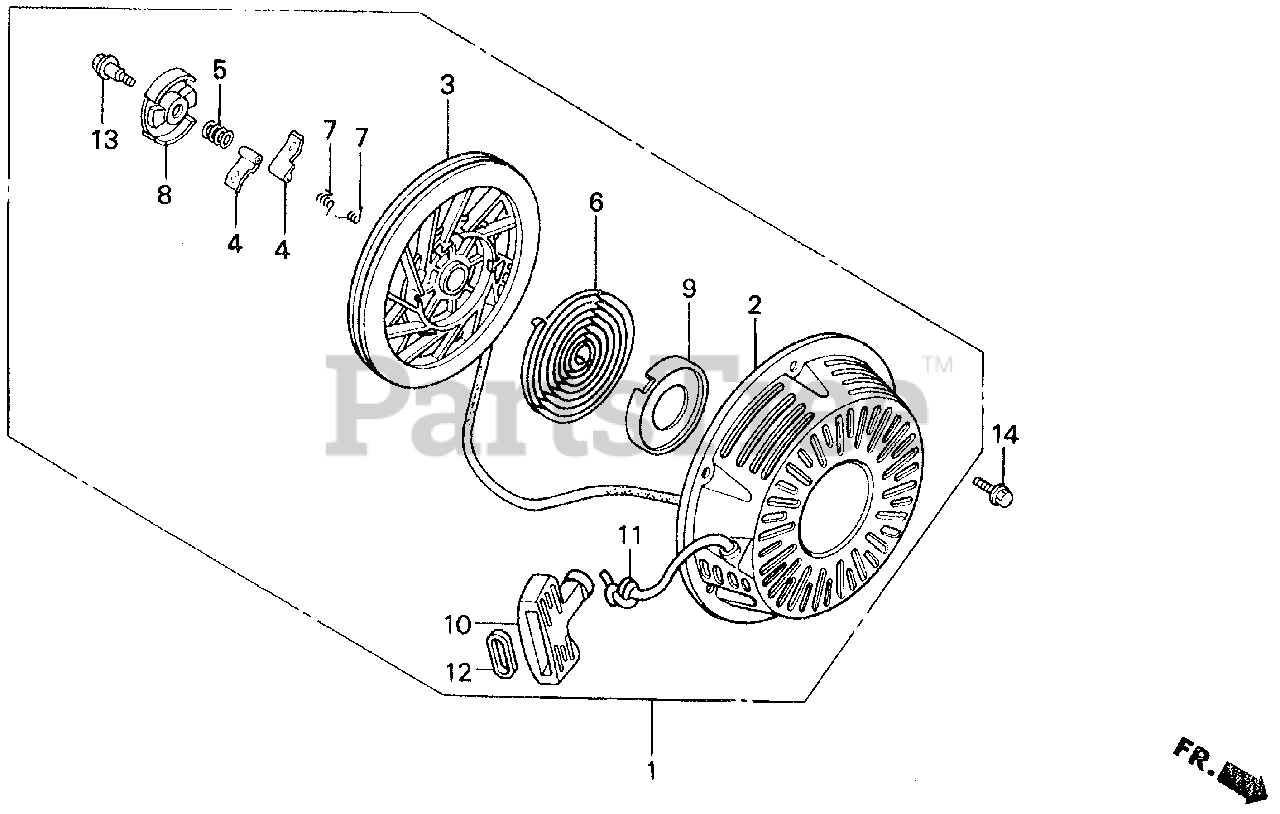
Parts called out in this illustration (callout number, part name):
1	STARTER ASSY., RECOIL *T68* (TSURUI BLUE)
1	STARTER ASSY., RECOIL *T80* (BAKERITE ORANGE)
2	CASE, RECOIL STARTER *T68* (TSURUI BLUE)
2	CASE, RECOIL STARTER
3	PULLEY, RECOIL STARTER
4	RATCHET, STARTER
5	SPRING, FRICTION
6	SPRING, STARTER RETURN
7	SPRING, RATCHET
8	RETAINER, SPRING
9	HOLDER, SPRING
10	GRIP, STARTER
11	ROPE, RECOIL STARTER (#6X64") (N/A: USE P/N 08560-ZG921-11)
12	GRIP, REINFORCEMENT
13	SCREW, CENTER
14	BOLT, FLANGE (6X10)
14	BOLT, FLANGE (6X8)
